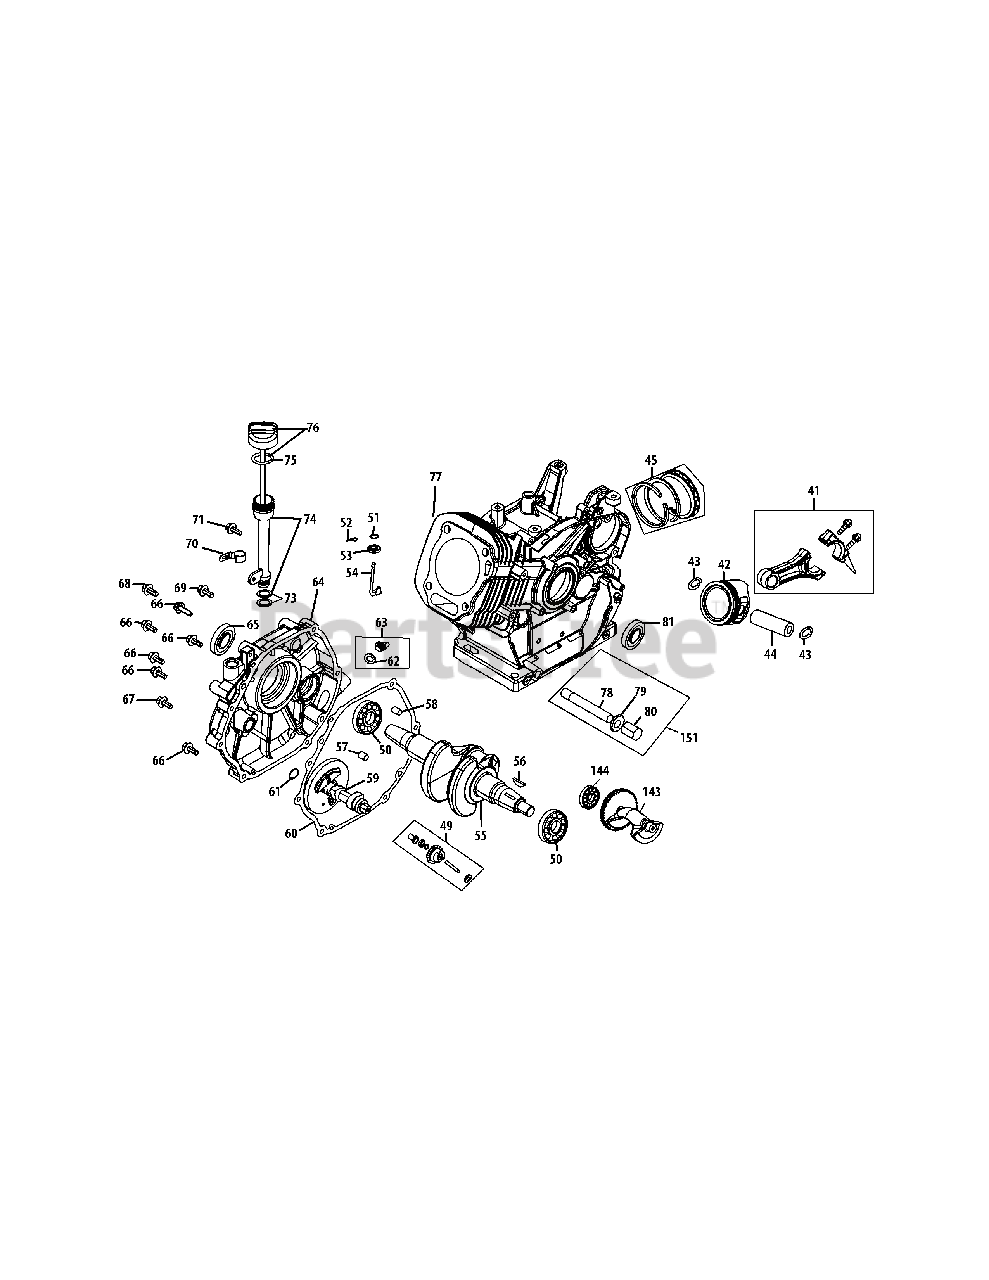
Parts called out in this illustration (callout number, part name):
41	Connecting Rod Assembly
42	Piston
43	Piston Pin Snap Ring
44	Piston Pin
45	Piston Ring Set Kit
49	Governor Gear/Shaft Assembly
50	Radial Ball Bearing, 6202-P6
51	Washer 20Od X 8Id X 0.8
52	Cotter Pin
53	Governor Seal
54	Governor Arm Shaft
55	Crankshaft Kit
56	Woodruff Key
57	Dowel Pin 9×12
58	Dowel Pin 7×14
59	Camshaft Assy.
60	Crankcase Cover Gasket
61	Washer 16×24×0.5
62	O-Ring 16×3
63	Oil Fill Plug Assembly
64	Crankcase Cover Kit
65	Oil Seal, 30×46×8
66	Bolt M8×38
67	Bolt M8×45
68	Bolt M8×35
69	Bolt M6×16
70	Oil Tube Support Bracket
71	Bolt M6×8
73	Oil Fill Tube O-Ring
74	Oil Fill Tube Assembly
75	Dipstick O-Ring
76	Dipstick Assembly
77	Crankcase Kit
78	Oil Drain Pipe Assy.
79	Washer 10×16×1.5
80	Oil Drain Plug
81	Oil Seal 35×52×7
143	Balance Gear Assembly
144	Bearing, 6207-P6
151	Oil Drain Assembly
